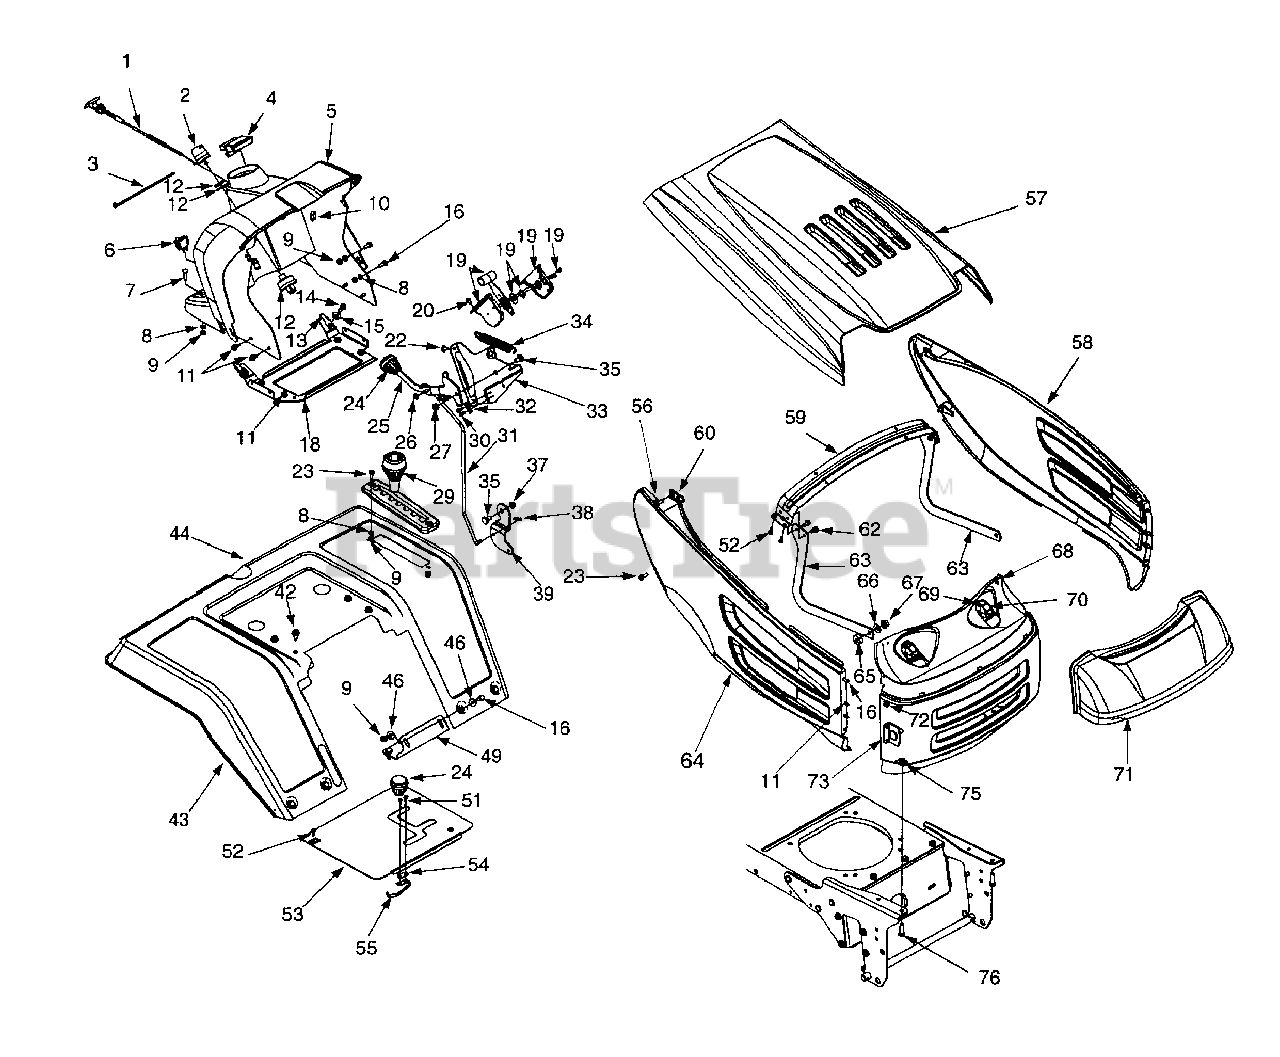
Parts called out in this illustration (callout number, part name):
1	Choke Cable
2	Ignition Key
3	Cable Tie
4	Ammeter
5	Dash Panel
6	Light Switch
7	Carriage Bolt 1/4-20 x 1" Lg.
8	L-Wash. 1/4" I.D.
9	Hex Nut 1/4-20 Thd.
10	Choke Retainer
11	Hex Wash. Hd. AB-Tapp Scr.
12	Ignition Switch
13	Speed Nut 1/4-20 Thd.
14	Hex Wash. Hd. TT-Tapp Scr.
15	Fl-Wash. 1/4" I.D.
16	Hex Bolt 1/4-20 x .62" Lg.
20	Truss Mach. AB-Tap Scr.
22	Truss Mach. AB-Tap Screw 0.62"
23	Pan Hd. Mach. Scr. 1/4-20 x .75"
24	Knob
25	PTO Lever
26	Speed Cap Nut
27	Hex L-Nut 5/16-18 Thd.
30	Hex Wash. Hd. AB-Tap Scr.
31	Deck Connection Rod
32	Switch Plate
35	Shld. Bolt 1.62" Lg.
37	Hex L-Nut 5/16-18 Thd.
38	Hairpin Clip
39	Control Deck Pivot Bracket
42	Hex Wash. Hd. AB-Tapp Scr.
46	Bell-Wash. 1/4" I.D.
52	Truss Hd. B-Tapp Scr.
55	Spring Switch
56	Rubber Bumper
62	Hex Wash. Hd. TT-Tap Scr.
66	Spr. Washer
67	Flange L-Nut 3/8-16 Thd.
68	Retainer Nut
69	Socket
70	Lamp
71	Lens
72	Hex Sems Nut 1/4-20 Thd.
76	Hex Bolt 5/16-18 x 1" Lg.
